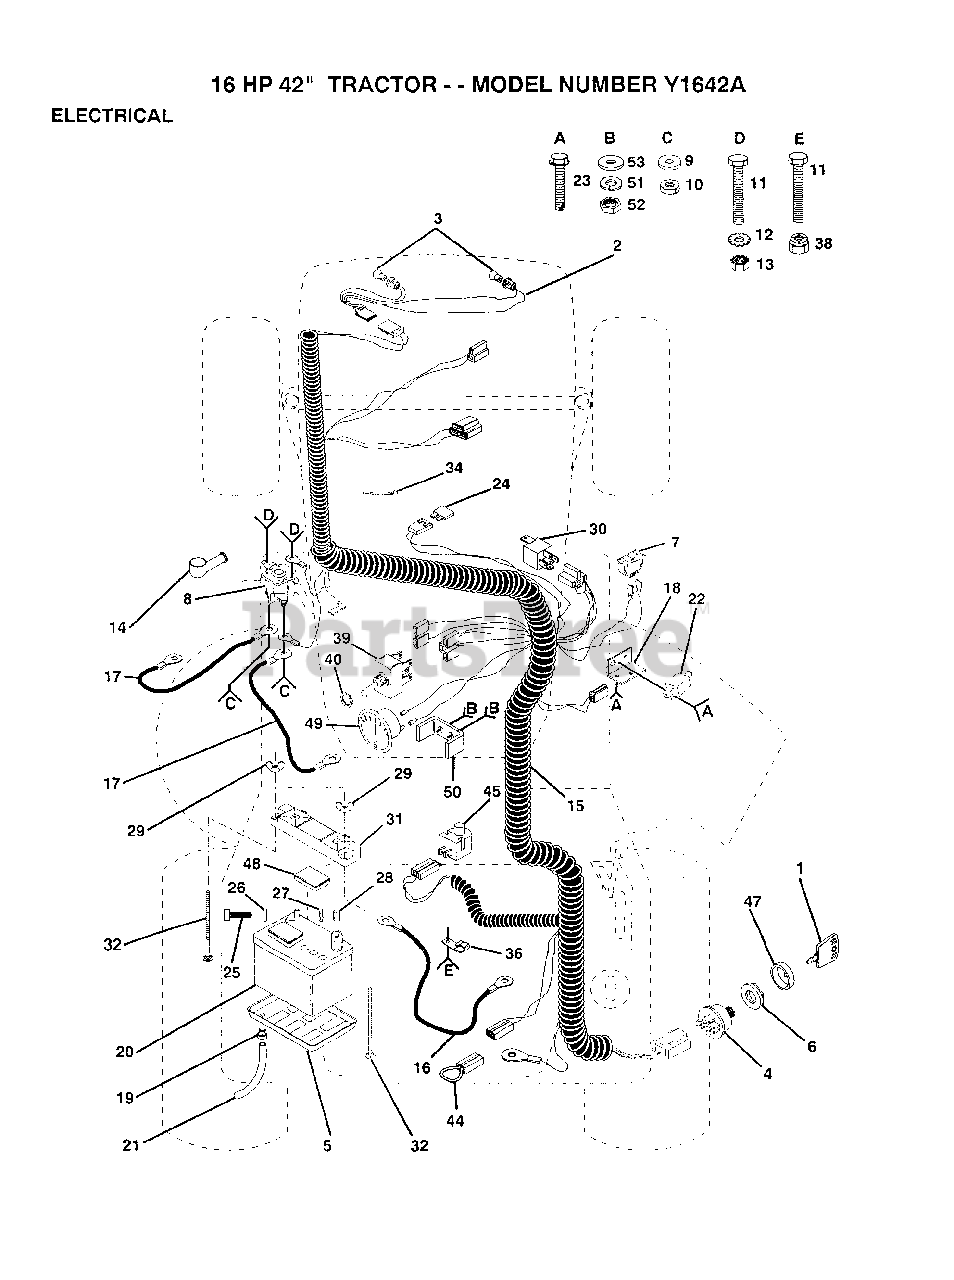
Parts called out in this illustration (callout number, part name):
1	KEY
5	"TRAY T, BATTERY"
6	NUT IGNITION
7	SWITCH LT
10	NUT
11	BOLT
13	NUT
15	"HARNESS,IGNITION"
16	CABLE T
17	CABLE-BATTERY T
18	BRACKET LT
19	HOSE CLAMP T
22	SWITCH-INTER. GT
23	SCREW
24	FUSE HYT
25	BOLT LT
26	WASHER
27	LOCKWASHER
30	RELAY ASSY T
32	BOLT
34	WIRE TIE
36	CLIPT
39	SWITCH.PTO.T
40	HEX NUT T
45	SWITCH SEAT
48	"CAP,BATTERY "
49	AMMETER T
53	WASHER
